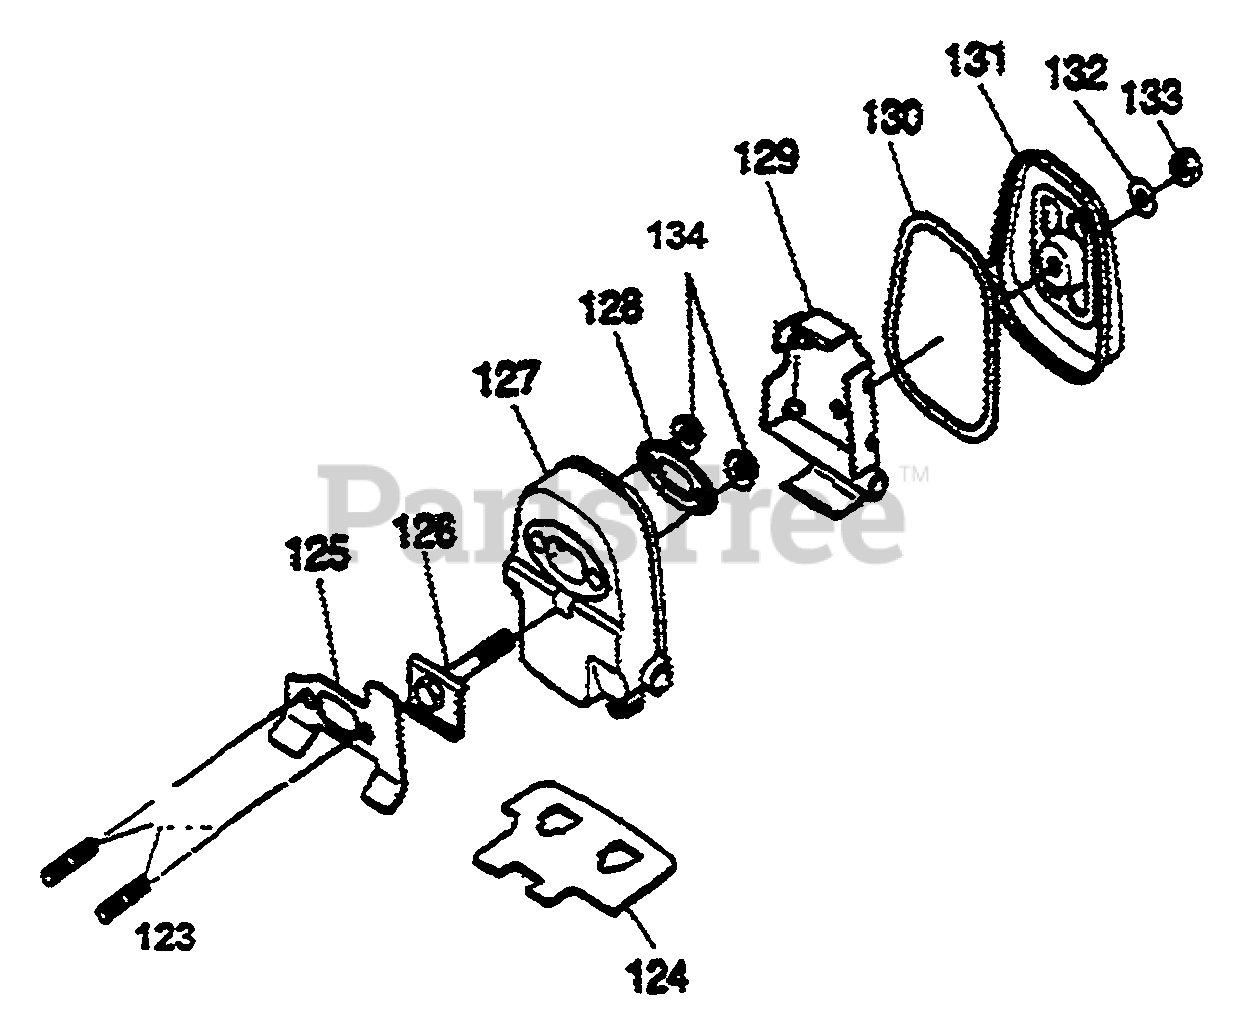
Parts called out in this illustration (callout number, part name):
125	GASKET MUFFLER
126	BOLT, FLANGE
127	BODY, MUFFLER
130	GASKET MUFFLER SEAL
131	LID, MUFFLER
132	WASHER,SEAL
